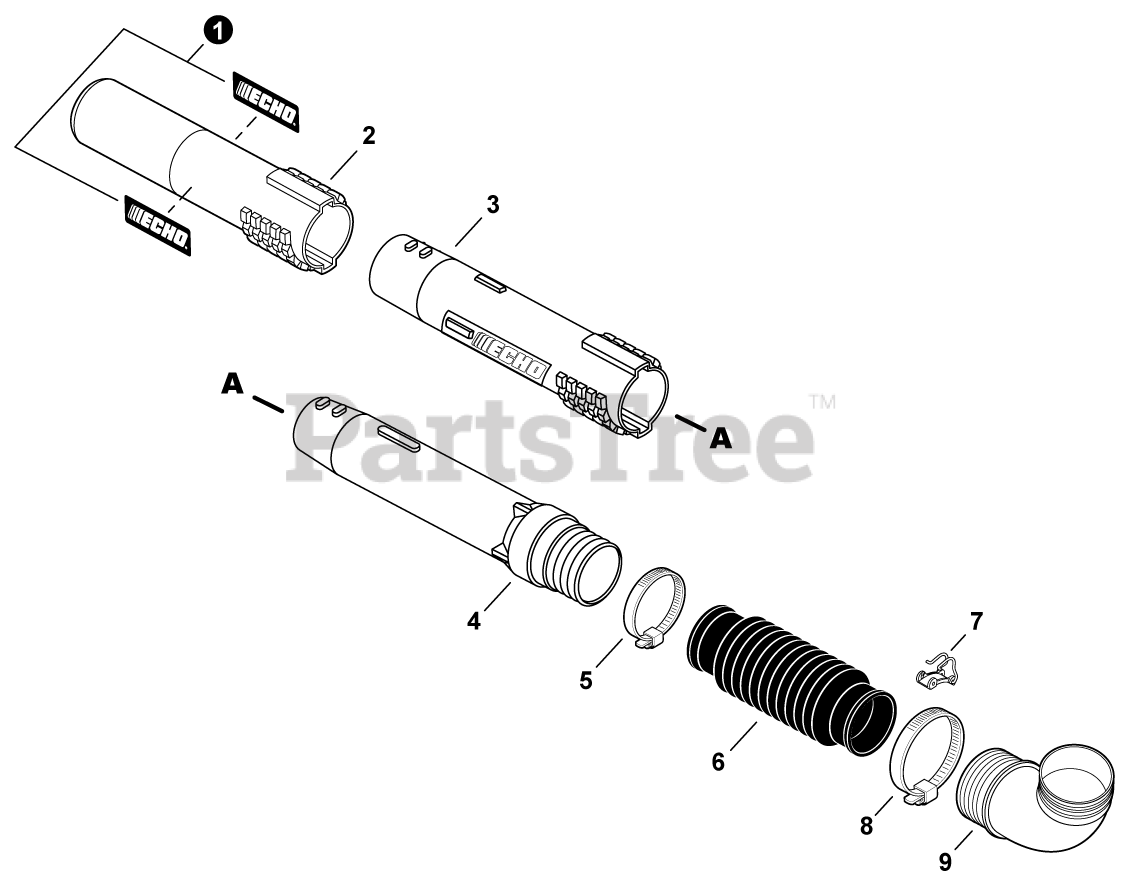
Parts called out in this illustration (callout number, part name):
1	LABEL - ECHO
2	TUBE, BLOWER - NOZZLE
3	TUBE, BLOWER - STRAIGHT
4	TUBE, BLOWER - SWIVEL
5	CLAMP 58.7 MM / 82.5 MM
6	FLEX PIPE, PB-755
7	CLIP, CABLE
8	CLAMP - BAND
9	TUBE, BLOWER - ELBOW
